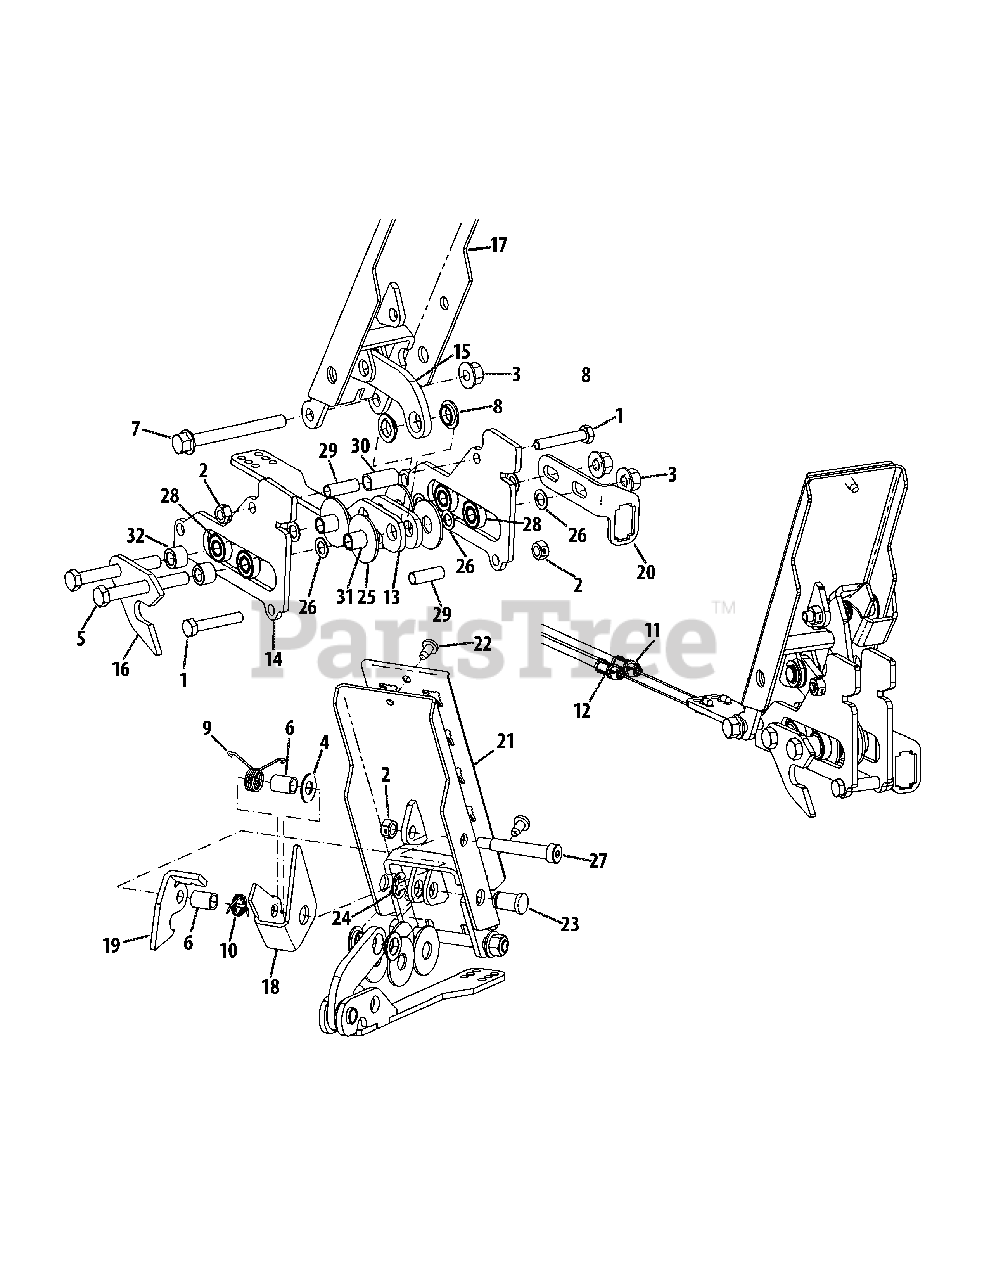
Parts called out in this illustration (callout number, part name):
1	Hex Screw, 5/16-18 x 1.75
2	Counter Lock Nut, 5/16-18
3	Flange Counter Lock Nut, 3/8-16
4	Washer, .416 x .875 x .046
5	Hex Screw, 3/8-16 x 3.00
6	Spacer, .380 x .500 x .667
7	Hex Screw, 3/8-16 x 3.50
8	Flange Bearing, .502 x .875 x .180
9	Torsion Spring
10	Torsion Spring
11	LH Brake Cable
12	RH Brake Cable
13	Brake Carrier Assembly
14	Brake Roller Guide Bracket
15	Brake Control Link
16	Lockout Plate
17	Brake Pedal Assembly
18	Park Engagement Bracket
19	Brake Hook Bracket
20	Brake Switch Mount Bracket
21	Brake Pedal Grip
22	Screw, 1/4-20 x .5
23	Pin, .500 x .804
25	Flat Washer, .531 x 1.5 x .08
26	Washer, .39 x .62 x .03
27	Shoulder Screw, 5/16-18 x .375 x 2.00
28	Bearing, .375 x .875
29	Spacer, .319 x .375 x 1.056
30	Spacer, .384 x .500 x 1.000
31	Spacer, .38 x .5 x .955
32	Spacer, .385 x .625 x .458
